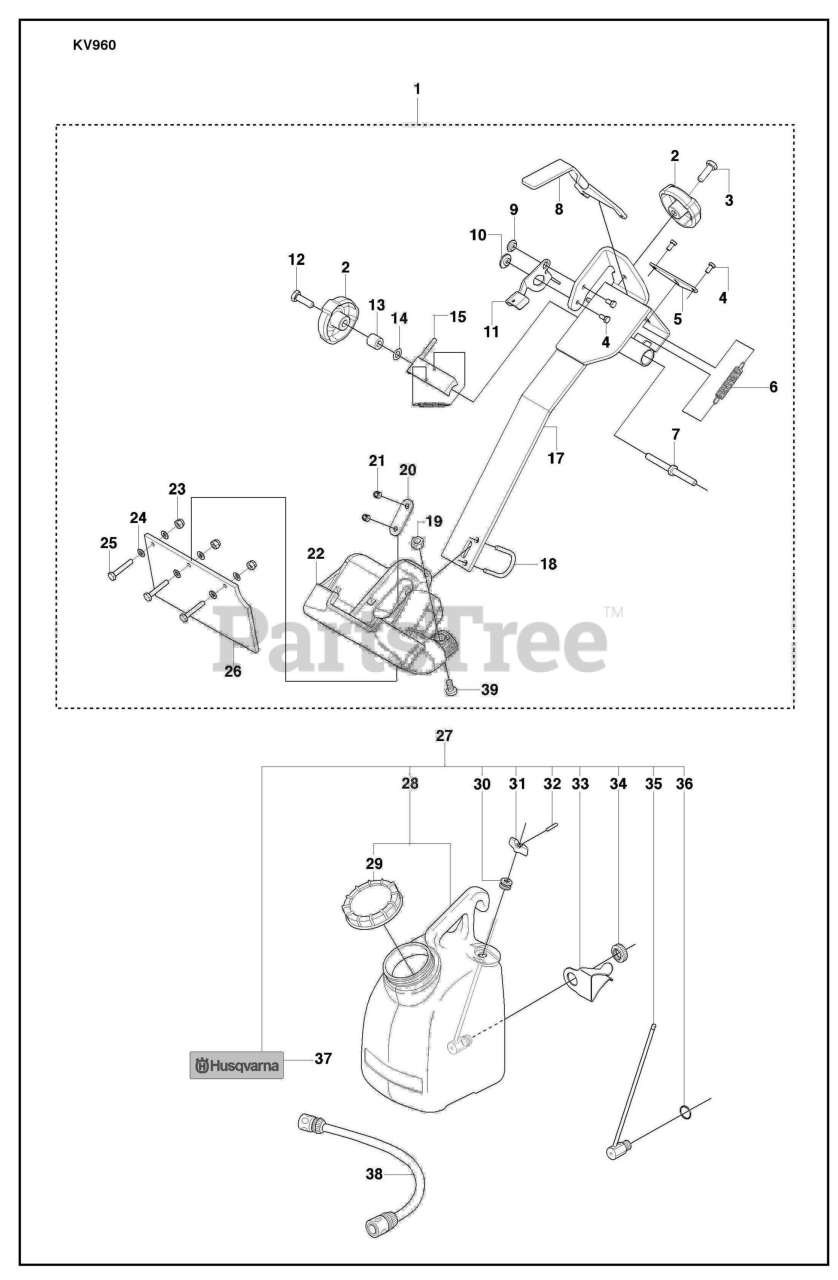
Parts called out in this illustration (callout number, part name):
1	HOLDER ASSY
2	TURNING KNOB
5	LOCKING PLATE
8	LOCKING LEVER
13	SPACING SLEEVE
14	CUP SPRING
19	NUT
27	WATER TANK ASSY
28	WATER TANK
30	ANTIVIBRATION ELEMENT
32	SPRING PIN
